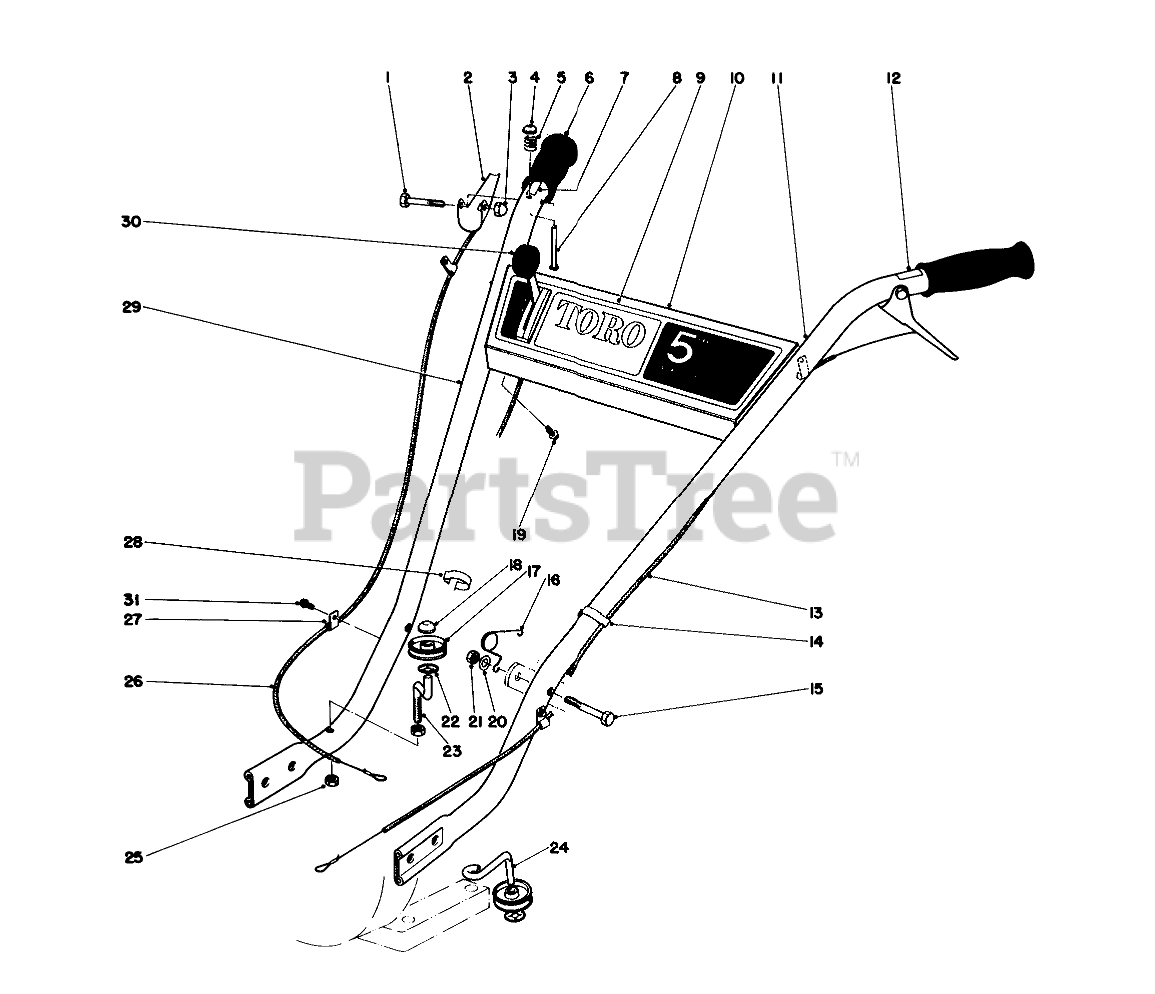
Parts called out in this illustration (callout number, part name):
1	SCREW-HH
2	LIFTBAIL
3	NUT-CAP
4	Push-On
5	COMPRESSION SPRING
6	Hand Grip
7	Decal-Fwd.
8	LOCK PIN
9	Decal-Escutcheon
10	Escutcheon Panel
11	Handle L.H.
12	Decal Rev.
13	REV CABLE ASM
15	SCREW-HH
16	Spring-Torsion
17	Pulley Cable
18	RETAINER PUSH ON
19	SCREW-HWHTF
20	WASHER-PLAIN
21	NUT-LOCK, CONE
22	PUSH ON RETAINER
23	Spindle-Fwd.
24	Spindle-Rev.
25	LOCKNUT
26	FWD CABLE ASM
27	3/16 SUPPORT
28	Boden Clip
29	RH HANDLE
30	THROTTLE CONTROL
31	10 X 1/2 SCREW
